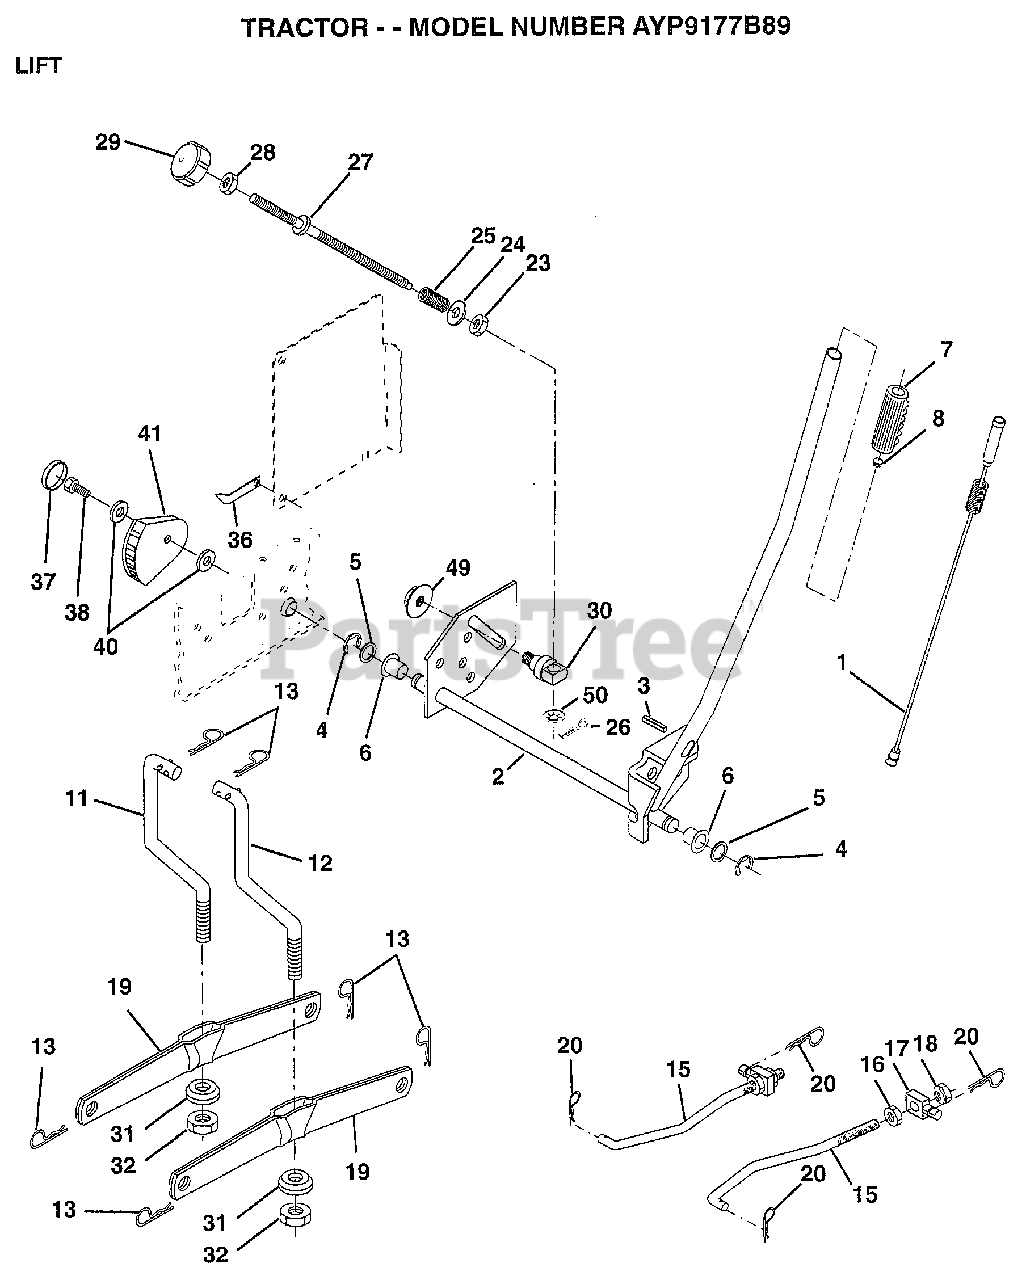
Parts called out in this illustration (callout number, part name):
1	WIRE ASM W.SPRING
2	"SHAFT ASM LIFT,RH"
3	PIN-GROOVE LT
5	WASHER
6	NYLON BEARING
7	GRIP HANDLE
15	LINK.FRONT
16	NUT
17	TRUNION
18	NUT LTV
19	ARM SUSP REAR
20	RETAINER SPRING
23	NUT T
24	WASHER
25	SPRING T
28	NUT
29	KNOB INF 3/8-16
30	TRUNNION
31	BEARING PVT LH
32	NUT.CROWNLOCK.3/8
36	POINTER-INDICAT
37	"PLUG,HOLE"
38	SCREW
40	WASHER
41	INDICATOR HEIGHT
49	NUT.HXFLG.LOCK.
